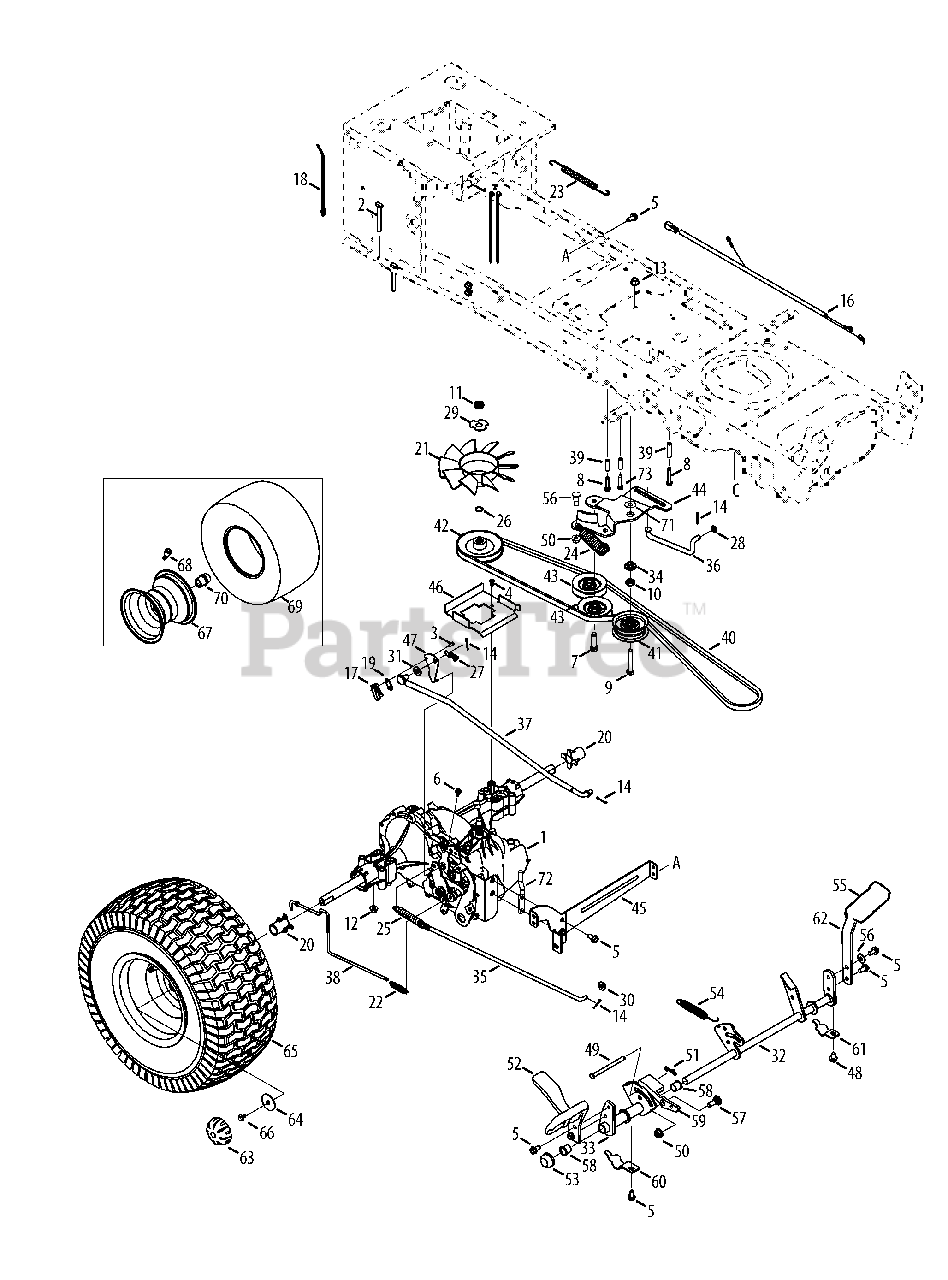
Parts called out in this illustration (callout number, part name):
1	Hydro Transmission
2	Hex Screw, 5/16-18:2.75
3	Screw, #8-18:0.500
4	Screw, #10-16:0.500
5	Taptite Screw, 5/16-18:.750
6	Taptite Screw, 1/4-20:0.375
7	Screw, Sems, 3/8-16, 1.500
8	Taptite Screw, 1/4-20:1.625
9	Hex Screw, 3/8-16:2.25
10	Jam Nut, 7/16-20
11	Nut, Jamlock, 1/2-20
12	Flangelock Nut, 5/16-18
13	Flangelock Nut, 3/8-16
14	Cotter Pin, 3/32:1.0
15	Cable Tie, 3/16 X .05 X 7.4
16	Jumper Harness
17	Short Spring Switch
18	Push Mount Cable Tie 7.5 LG
19	Insulator Nut Plate
20	Sleeve, .765 ID x 1.500 LG
21	Hydro Fan
22	Extension Spring, .48 OD X 2.03
23	Extension Spring, .500 DIA X 12.6 LG
24	Extension Spring, 1.00 DIA X 4.75
25	Extension Spring, .59 OD X 4.00 LG
26	Wire Ring
27	Extension Spring, .375 OD X 1.44 LG
28	Washer, Flat, .330 X .630 X .0635
29	Washer, Lock, TRANS HYDRO
30	Washer, Flat, .344 X .750 X .120
31	Washer, Flat, .407X.812X.135:HT
32	Brake Control Assembly
33	Hydro Pedal Bracket Assembly
34	Spacer, Shoulder, 1.375 X .380 X .183
35	Rod, Brake, Hydro
36	Rod, Transmission, Footpedal Bypass
37	Rod, Control, Hydro
38	Rod, Hydro Bypass
39	Spacer, .260 X .372 X 1.420 LG
40	Belt, V Type, Poly
41	Pulley, Idler, Flat 2.75 OD
42	Pulley, Input, 4.13 DIA
43	Pulley, Idler, V-Type x 3.06
44	Bracket, Idler, Center Double
45	Bracket, Mount, Hydro
46	Bracket, Support, Belt Disengage
47	Switch Actuator Bracket
48	Taptite Screw, 5/16-18:0.625
49	Clevis Pin, 5/16 x 3.985
50	Flangelock Nut, 3/8-16
51	Bow-Tie Cotter Pin
52	Control Pedal
53	Push Cap
54	Extension Spring, .63 DIA x 4.95 LG
55	Brake Pedal Pad
56	Scr, Shldr, .50 x .685 3/8-16
57	Shoulder Bolt, .500 x .270:3/8-16
58	Flange Bearing, .630 ID x .695 OD x .60
59	Cruise Latch
60	Pedal Support Bracket
61	Pedal Support Bracket, 5/8
62	Brake Pedal Bracket
63	Hub Cap
64	Washer, Flat, .350 x 1.59 x .062
65	Wheel Assembly
66	Screw, 5/16-24 x .750
67	Rim Assembly, Plastic Bead, 46"
68	Tubeless Air Valve
69	Tire, 20 x 8 x 8
70	Axle Hub
71	Washer, Flat, .385 x 1.0 x .030
72	Belt Keeper Rod
73	Screw, Self Tapping, 1/4-20 x 1.75
